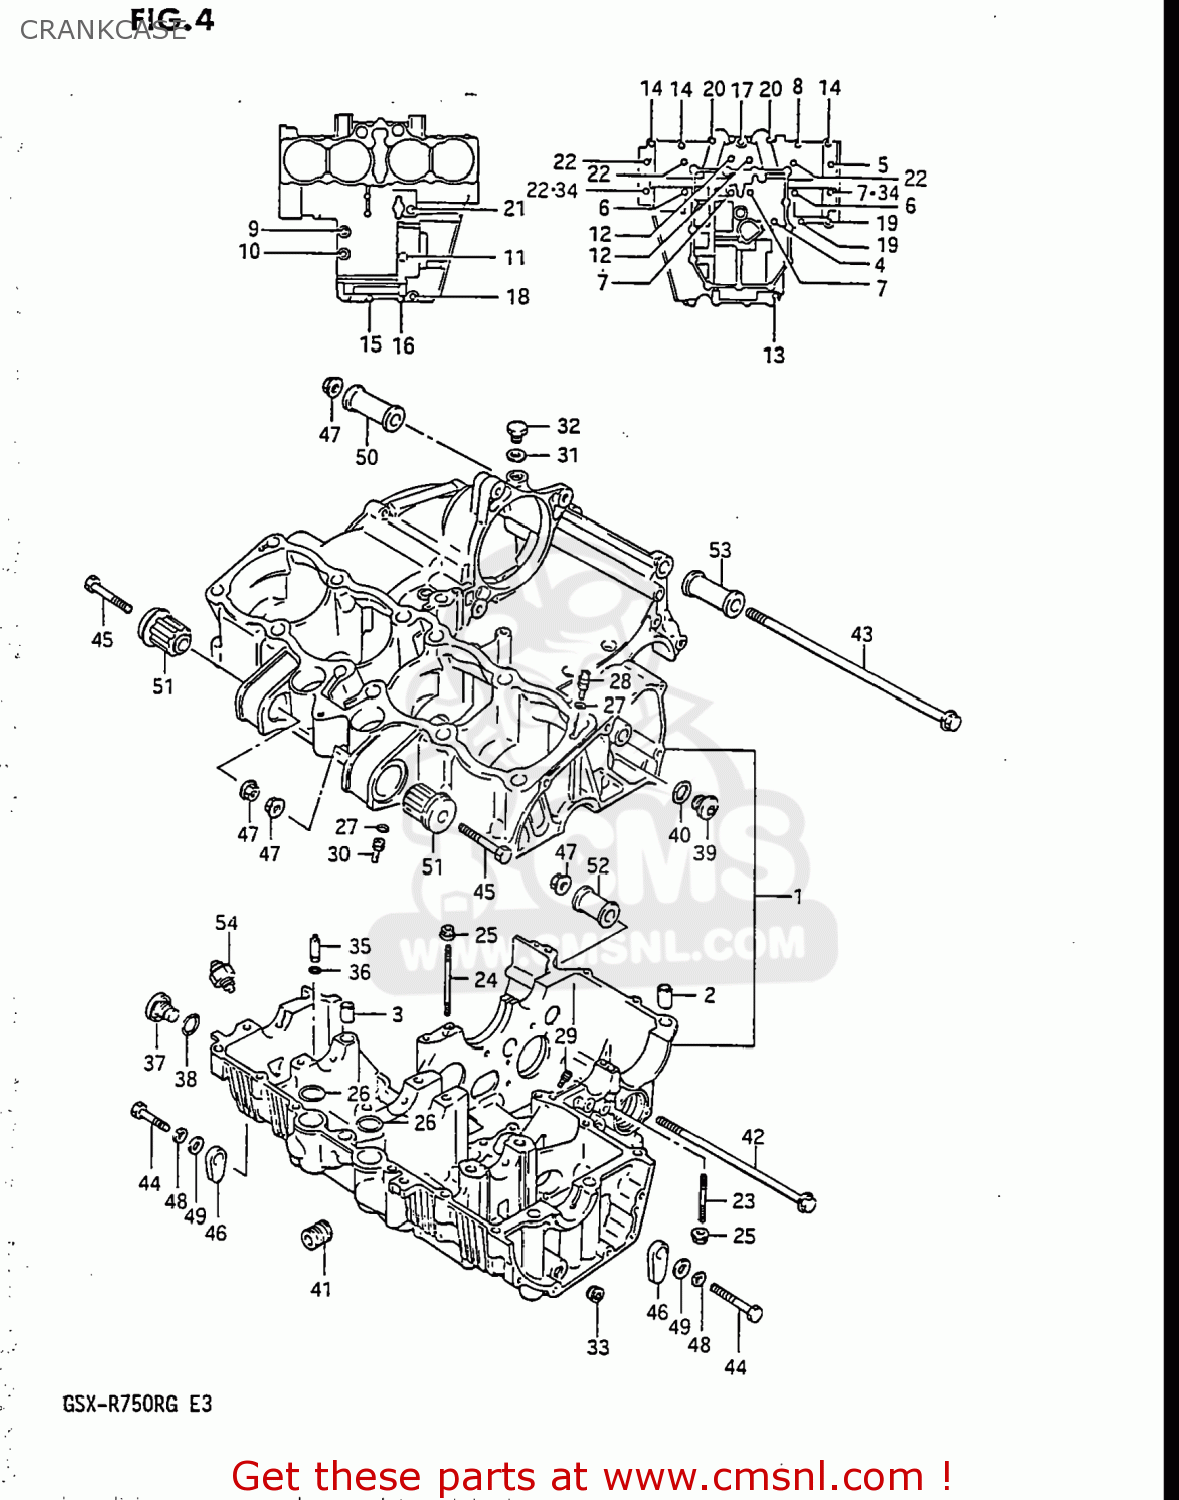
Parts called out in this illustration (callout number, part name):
1	CRANKCASE SET
2	PIN(10.4X13X22)
3	PIN (11X20)(SUS)
4	BOLT(6X105)
5	BOLT(8X105)
6	BOLT(8X125)
7	BOLT(8X115)
8	BOLT 6X35
9	BOLT
10	BOLT
11	BOLT
12	BOLT
13	BOLT 8X60
14	BOLT 6X35
15	BOLT
16	BOLT
17	BOLT 6X50
18	BOLT ,6X60
19	BOLT
20	BOLT
21	BOLT
22	BOLT(8X95)
23	STUD BOLT
24	STUD BOLT
25	NUT
26	O RING(D:2.5,ID:21)
27	O RING(D:1.2,ID:4)
28	JET,AIR
29	JET
30	JET,OIL
31	GASKET(12.1X16.2X3.7) (NAS)
32	PLUG(12X9)
33	PLUG(1/4PT,H:7.5)
34	GASKET(8.5X17X2.3) (NAS)
35	VALVE ASSEMBLY,PISTON OIL
36	O RING(D:1.2,ID:4.7)
37	PLUG
38	O RING(D:2.4,ID:16.8)
39	PLUG
40	GASKET(14X19.2X2) (NAS)
41	UNION,OIL STAND
42	BOLT(10X180)
43	BOLT(10X255)
44	BOLT 10X55
45	BOLT 10X55
46	NUT
47	NUT
48	LOCK WASHER
49	WASHER
50	SPACER,ENGINE MOUNT
51	BUSH,ENGINE MOUNTING
52	SPACER,ENGINE MOUNT
53	SPACER
54	SWITCH ASSEMBLY
